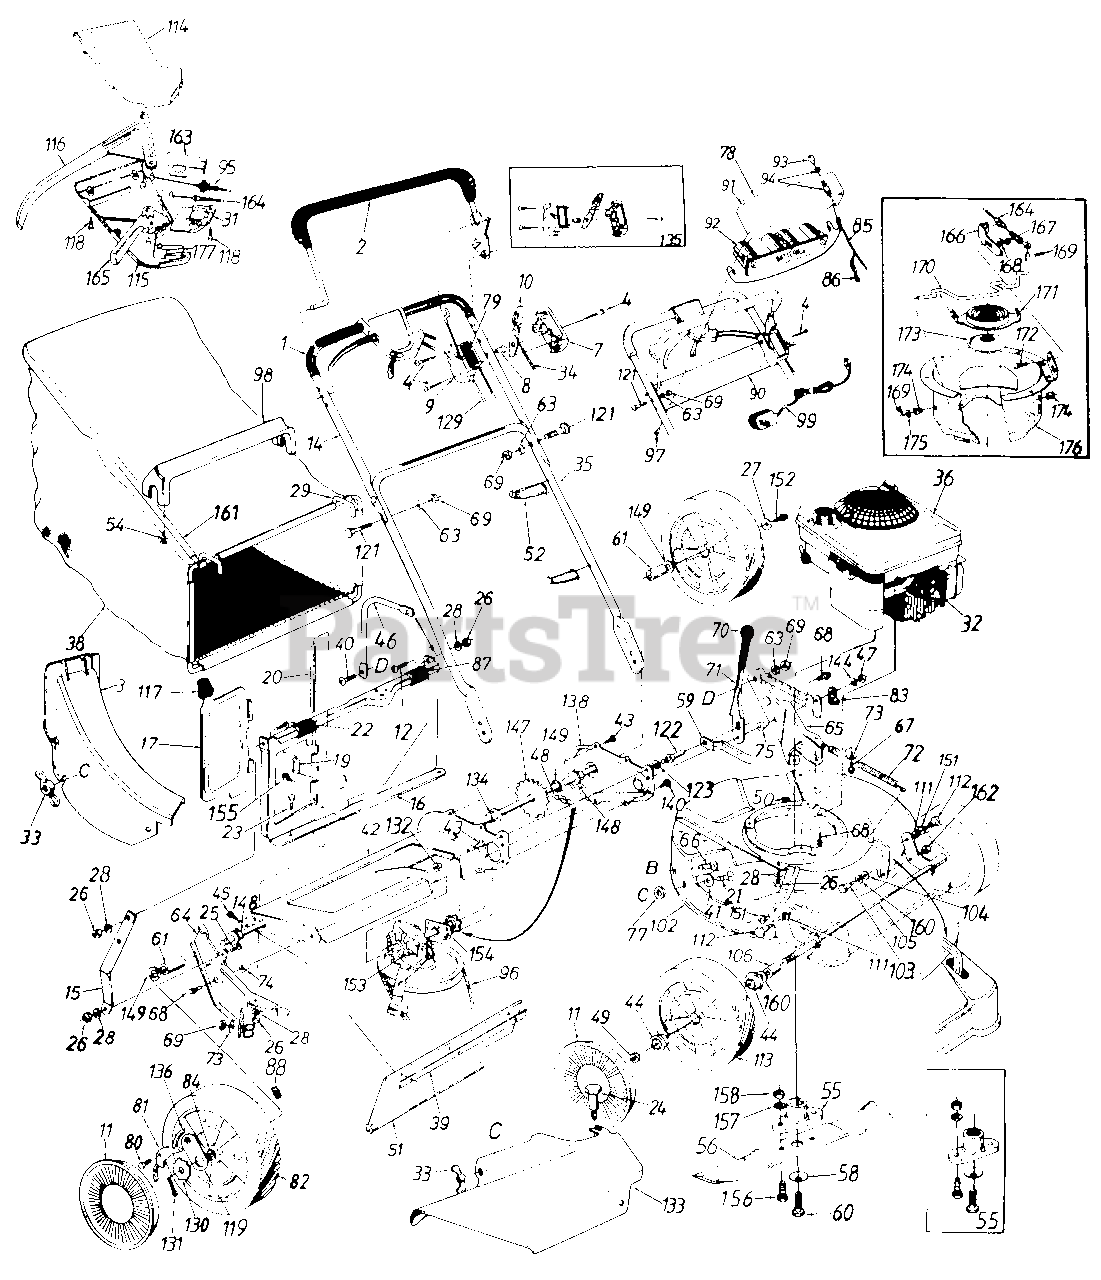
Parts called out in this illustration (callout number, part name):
1	Foam Grip-2 Req'd.
2	Control Handle Ass'y.-L.H.
3	Rear Discharge Chute Ass'y.
4	Truss Mach. Scr. #12 x 1.50" Lg.
7	Control Panel Half
8	Control Disc Pin
9	Clutch Panel Half
10	Throttle Control Lever
11	Hub Cap
12	Truss Mach. Scr. 1/4-20 x .62" Lg.
14	Upper Handle-Painted
19	Torsion Spring
21	Carriage Bolt 1/4-20 x .62"
22	Truss Mach. Scr. 1/4-20 x 3/4" Lg
23	Hex Bolt 1/4-20 x .50" Lg.
24	Shoulder Bolt .312 Dia. x .18 Lg.-Special
25	Hex Bolt 1/4-20 x .62" Lg.
26	Hex Nut 1/4-20 Thd.
27	Bell-Wash. 1/4" I.D.
28	L-Wash. 1/4" I.D.
31	S.P. Control Cover
32	Spark Plug Insulator
33	Wing Nut w/Washer
34	Throttle Control Wire 61"
35	Lower Handle-Painted
36	Engine
38	Grass Bag
39	Retaining Strip
40	Truss Mach. Scr. 5/16-18 x .75"
41	Fl-Wash. .344" I.D. x .62"
44	Flange Ball Bearing 1/2" I.D.
45	Hex AB-Tap Scr. 1/4 X .62"
46	Catcher Panel Support Arm
47	Hex Patch L-Nut 3/8-24 Thd.
48	#48 Chain .500" Pitch x 30 Links
49	Hex L-Nut 1/2-20 Thd.
51	Rear Flap 3.75" x 17.30" Lg.
52	Cable Tie
54	Hex AB 0 Scr. #12 x 1.25" Lg.
55	Blade Adapter Kit
56	21" Blade
58	Bell-Wash. .46" I.D.
59	Height Adj. Connecting Arm
60	Hex Bolt 7/16-20 x 1.5" Lg. (Grade 5)
61	Spacer .513" I.D. x .703" O.D. x .69" Lg.
63	L-Wash. 5/16" I.D.
64	R.H. Handle Wheel Brkt. Ass'y.
65	L.H. Handle Wheel Brkt. Ass'y.
66	Carriage Bolt 5/16-18 x .62"
67	Hex Wash. Hd. B-Tap Scr. 5/1 6-1 8
68	Hex Wash. Hd. TT-Tap Scr. 3/8-1 6
69	Hex Nut 5/16-18 Thd.
71	Height Adj. Lever
72	Extension Spring .75" O.D. x 8" Lg.
73	Bell-Wash. 5/16" I.D.
74	Spacer
75	Shld. Spacer .500" Dia.
77	Bolt Retainer 1/4 x .50" O.D.
78	Instruction Label
79	Control Label
80	Shld. Scr. .342" Dia. x .268
81	Pawl
82	Wheel Ass'y. Comp.
84	Bearing 1/2" I.D.
85	Wire Harness
86	Plug
88	Flat Weld Nut 1/4-20 Thd.
90	Lower Battery Tray
91	Upper Battery Tray
92	12 Volt Battery
93	Key
94	Key Switch
95	S.P. Cable
96	"V"-Belt
97	Hex AB-Tap Scr. 1" Lg.
99	Battery Charger
102	21" Deck Ass'y.
103	Shld. Bolt .5" Dia. x .295
104	Bell-Wash. .515" I.D. x 1.0" O.D.
105	Front Axle Ass'y.
106	Sleeve .526" I.D. x .690" O.D. x .880" Lg.
111	Intern. L-Wash. 3/8 I.D.
112	Shld. Bolt .575" Dia. x .42
113	Wheel Ass'y. Comp.
114	Self-Propelled Control Cover
115	Self-Propelled Control Cover
116	Control Lever
117	Door Grip
118	Fl-"C"-Sunk Hd. Tap Scr. #10 x 75n Lg.
119	Pawl Plate
121	Curved Carr. Bolt 5/16-18 x 1.38" Lg .
122	Shld. Pin 3/8-24 x 1.43" Lg.
123	L-Wash. 3/8" I.D.
129	Control Cable 46" Lg.
130	Ratchet Wheel 1.62" O.D.
131	Cotter Pin 1/8" Dia. x 1.00" Lg.
132	Hex Jam Nut 3/8-24 Thd.
133	Side Chute Deflector Ass'y.
134	Hex Flange Bearing
135	Kit-Control Housing Comp.
136	Spring-Nylon
144	Fl-Wash. .385" I.D. x .87"
147	Rear Shaft Ass'y. 21.94" Lg.
148	Hex Flange Bearing .506" I.D. Plastic
149	Fl-Wash. .531" I.D. x .930"
151	Flanged Nyliner Brg.
152	Hex Bolt 1/4-20 x .62" Lg. (Grade 5)
153	Transmission Comp.
154	Hex Bearing Cup
155	Hex B-Tap Scr. #10 x .38
156	Hex Scr. 3/8-24 x 1.0" Lg.
157	L-Wash. 3/8" I.D.
158	Hex Nut 3/8-24 Thd.
160	Fl-Wash. .51 I.D. x .75" O.D.
162	Hex Jam Nut 3/8-16 Thd.
163	3 Tooth Rack Gear Insert
164	Spd. Control Cable-50" Lg.
165	6-Spd. Shift Lever
168	Hex Cent. L-Nut 1/4-20 Thd.
169	Cot-Pin 3/32" Dia. x .75" Lg.
171	Movable Pulley Half Ass'y.
172	Carr. Bolt 1/4-20 x .50" Lg.
173	Spined Pulley Half
174	Flanged Bushing
175	Fl-Wash. .328" I.D. x .68" O.D.
176	Cable Mtg. Brkt. Ass'y.
177	Shift Lever Spring
